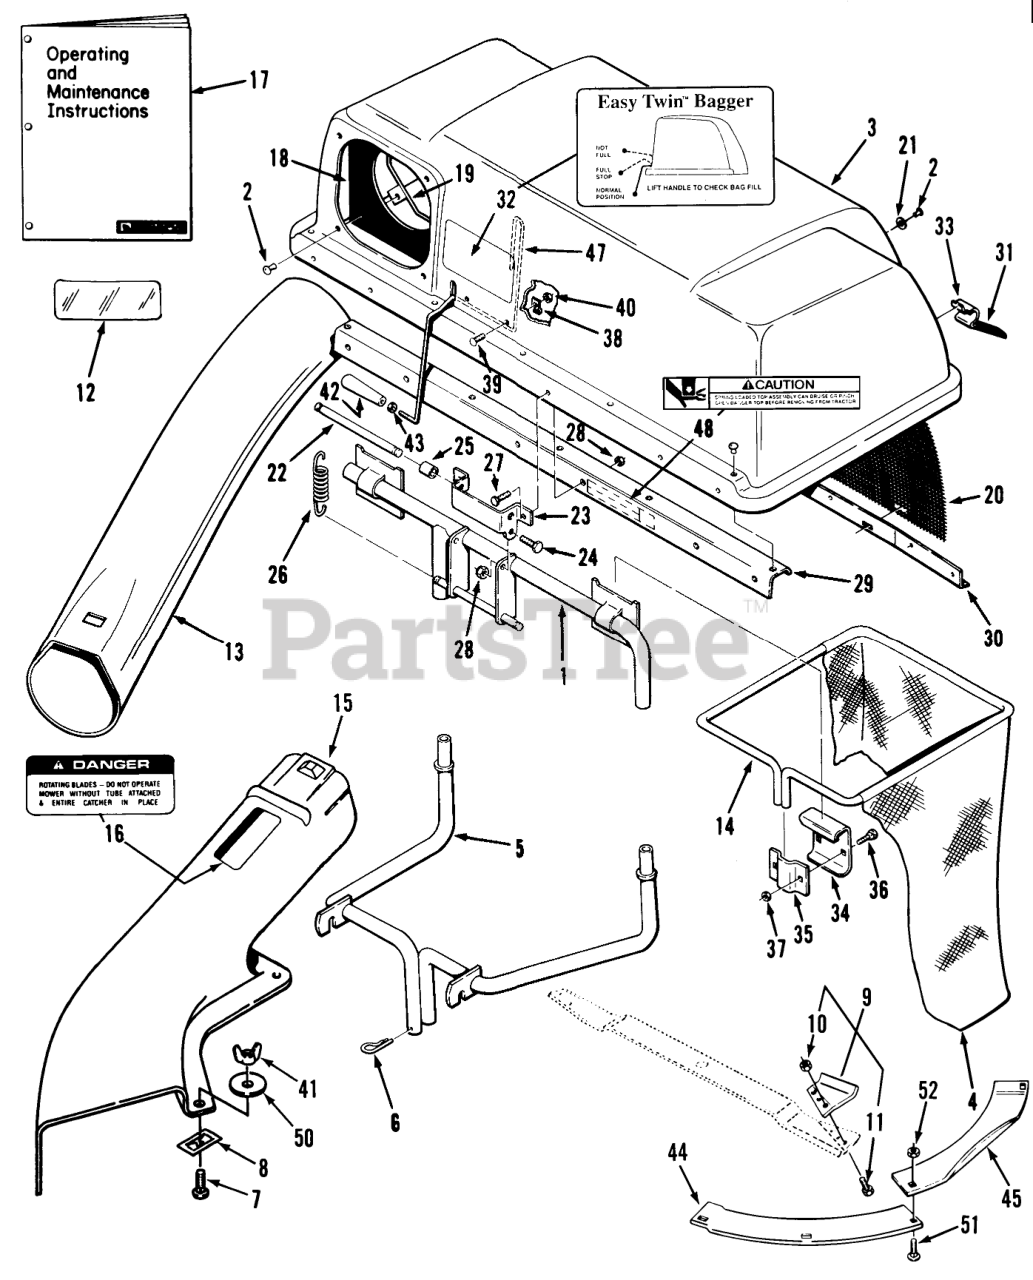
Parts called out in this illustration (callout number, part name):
1	FRAME ASM
2	RIVET-BLIND
3	TOP-BAGGER
4	BAG-18" DEPTH
5	ASM-QUICK ATTACH B
6	Hairpin
7	Bolt-Carriage
8	SPEED NUT 1/4-20
9	Lift Tab Kit (includes items 10 & 11)
10	BOLT 5/16-18X5/8
11	NUT-LOCK 5/16-18
12	DECAL-OVERLAY
13	CHUTE-BAGGER (L)
14	Bag Frame
15	Discharge Elbow (includes items 16)
16	DECAL-DANGER
17	Operating and Maintenance Instructions
18	Chute Seal
19	CLAMP-SEAL
20	SCREEN-BAGGER
21	Washer
22	PIN-SPRING
23	HINGE-BAG TOPB
24	Bolt
25	SPACER
26	SPRING-EXTENSION
27	BOLT
28	NUT
29	Bagger-Stiffener
30	SUPPORT-SCREEN B
32	Decal-Full Bag Test
33	Latch-Bag
34	Bag Hanger
35	Clamp
36	Bolt
37	Nut
38	CLIP
39	Screw
40	Nut
41	Nut-Wing
42	HANDLE-TAPERED
43	Nut
44	PLATE MOWER RING B (NS)
45	PLATE MOWER B
47	FEELER-FILL, BAG
48	DECAL-CAUTION
50	WASHER
51	Bolt
52	Nut
